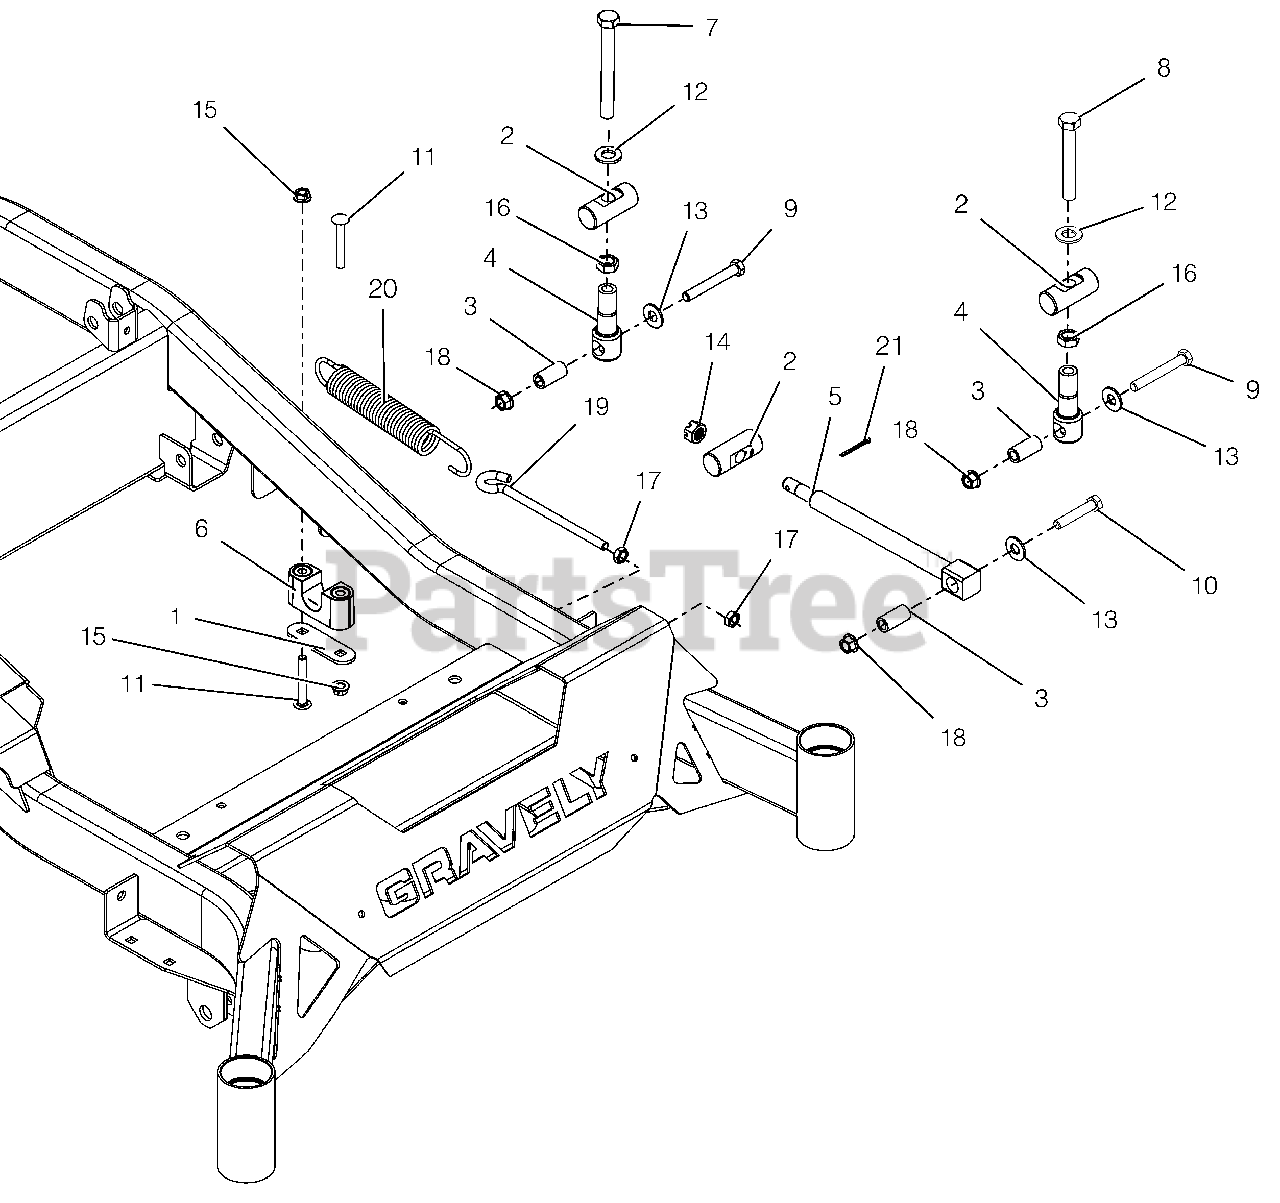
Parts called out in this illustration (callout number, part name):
1	PLATE, BEARING SUPPORT
2	PIN, DECK LIFT
3	SPACER, DECK LEVELING
4	LINK, DECK LIFT FORMED
5	DRAG,LINK-HD
6	ASM-BUSHING, DECK LIFT
7	@BLT-HEX .5-13-4.5GR8 FULL THD
8	BLT-HEX .50-13X3.50 GR5 FTH
9	BLT-HEX .38-16X2.75 GR8 YWZC
10	@BLT-HEX .38-16X2.00 GR5 YWZC
11	BLT-RDHDSQSHNK .31-18X2.25 YWZ
12	FLATWASHER 1/2 SAE HARD 15906
13	@WSHR-FL-STL.438X1.00X.083 YWZ
14	NUT-SL .50-13
15	@NUT-LK-CTR-FLG .31-18 YZ GR F
16	NUT-JAM .50-13 YWZC
17	NUT-HEX-JAM .375-16 YWZC
18	@NUT-LK-TOP-FLG .38-16 YWZC
19	BOLT,.38-16 X 5.25-.62 DIA EYE
20	SG-TENS .162X1.25X8.25 WLD 25
21	@PIN-CTR .12X1.25 EXTPRSQCT YZ
